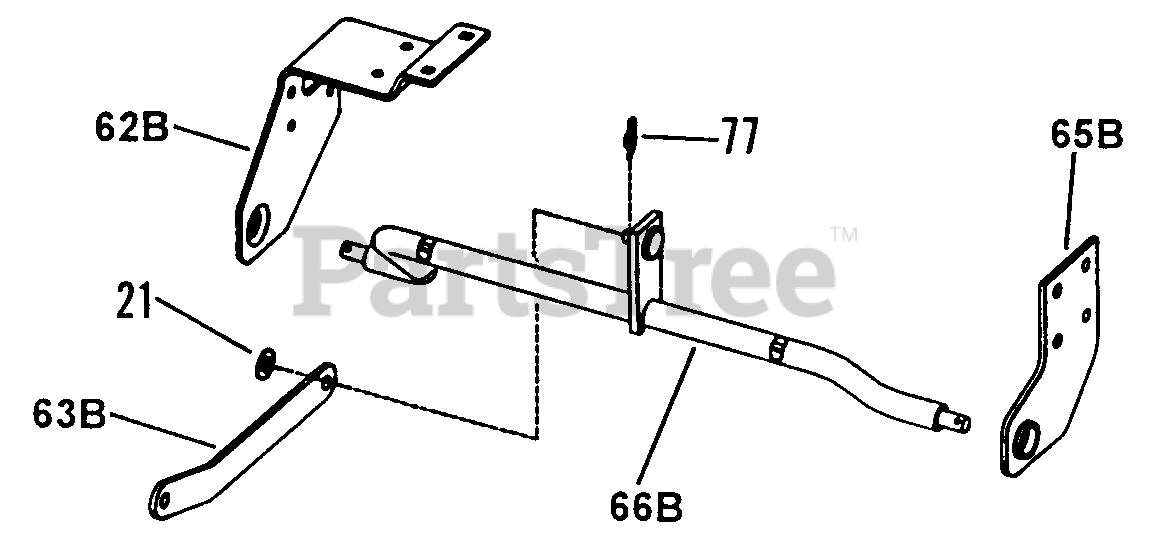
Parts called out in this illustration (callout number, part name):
21	WASHER, 3/8 Bright Zinc, Flat
62B	BRACKET, Rear Lift/PTO Lever
63B	LINK, Lift
65B	BRACKET, Rear Hanger - LH
66B	WELDMENT, Rear Lift
77	COTTER PIN, 1/16 x 1-7/32" Self Lock
